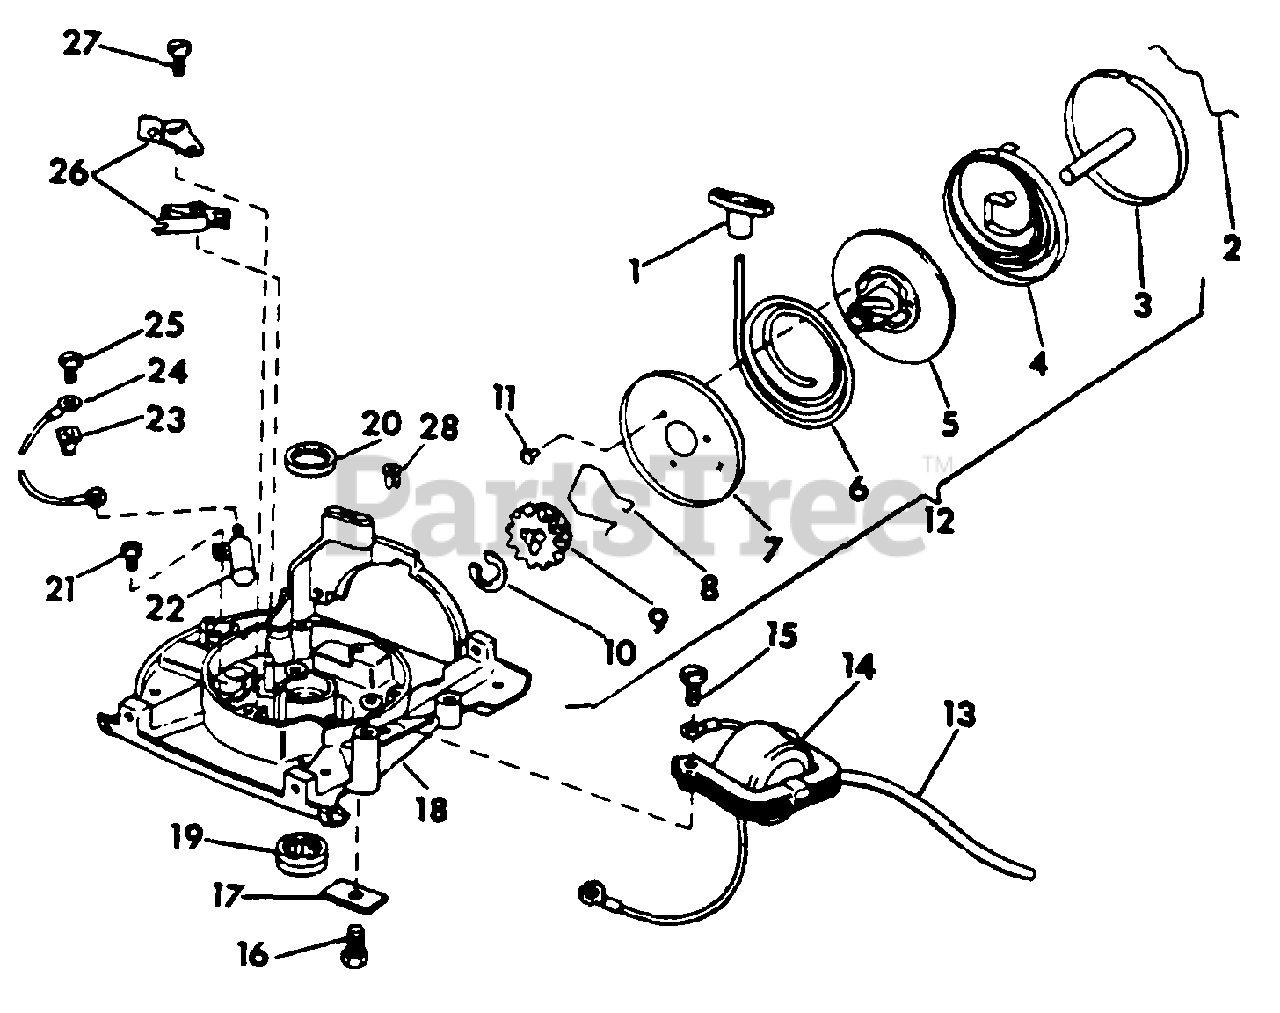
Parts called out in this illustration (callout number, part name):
1	HANDLE, STARTER
2	SPRING, STARTER ROPE RETAINER
3	SPRING, CUP & PIN
4	SPRING, STARTER
5	PULLEY, STARTER
6	ROPE, STARTER - 53 IN.
7	PLATE, STARTER PULLEY
8	SPRING, STARTER PINION
9	PINION, STARTER
10	RING, RETAINER
11	SCREW, THD CUTTING STARTER
13	HIGH TENSION LEAD ASSY
14	COIL & LAMINATION ASSY
15	SCREW, LAMINATION MTG
16	SCREW, STARTER ATT
17	CLAMP, STARTER PIN
18	ARM PLATE ASSY, BRG & OIL SEAL
19	BEARING NEEDLE
21	SCREW, CONDENSER MTG
22	CONDENSER & NUT ASSY
23	GROMMET, NYLON
24	TERMINAL & LEAD ASSY
25	SCREW, SHUT-OFF SWITCH
26	BREAKER BASE & ARM
27	SCREW, BREAKER BASE
28	GROMMET, COVER MTG
